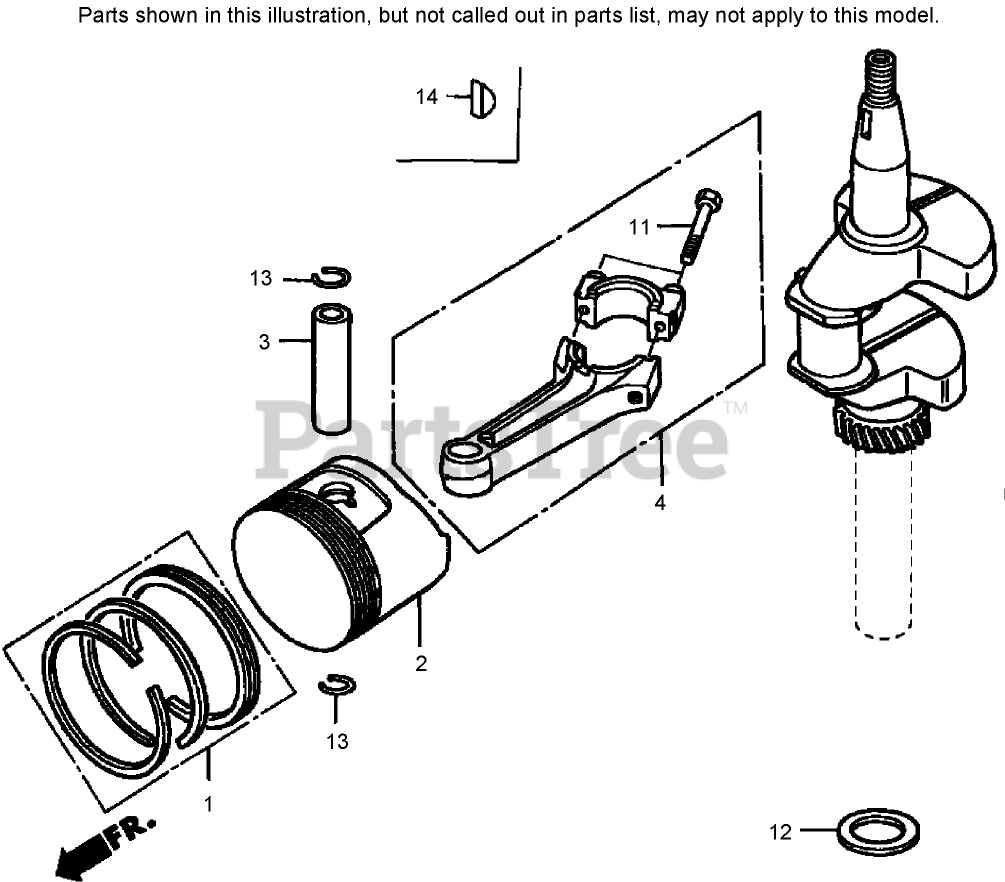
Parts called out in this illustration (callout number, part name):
1	RING SET-PISTON (STD)
1	RING SET-PISTON (OS 0.25)
1	Ring Set-Piston (OS 0.50)
1	RING SET-PISTON (OS 0.50)
1	Ring Set-Piston (0.75)
1	RING SET-PISTON (0.75)
2	Piston (STD)
2	PISTON (STD)
2	Piston (OS 0.25)
2	PISTON (O S 0.25)
2	PISTON (O S 0.50)
2	Piston (0.75)
3	Pin-Piston
4	CONNECTING ROD ASM
4	CONNECTING ROD ASM (US 0.25)
6	Crankshaft (N1 TYPE)
11	BOLT-ROD, CONNECTING
12	WASHER-THRUST (25.6 mm)
13	CLIP-PIN, PISTON (18 mm)
